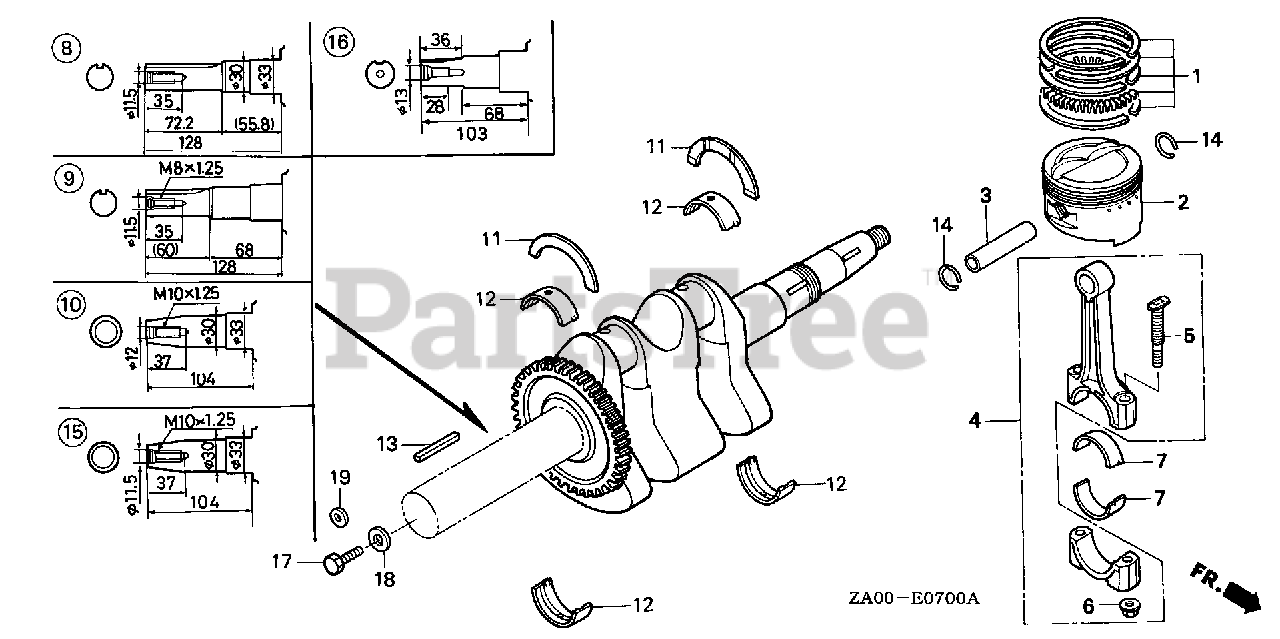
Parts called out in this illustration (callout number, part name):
1	RING SET, PISTON (STD) (RIKEN)
1	RING SET, PISTON (0.25) (RIKEN)
1	RING SET, PISTON (0.25) (TEIKOKU)
1	RING SET, PISTON (0.50) (TEIKOKU)
2	PISTON (STD)
2	PISTON (0.25)
2	PISTON (0.50)
3	PIN, PISTON
4	ROD ASSY., CONNECTING
5	BOLT, CONNECTING ROD
6	NUT, CONNECTING ROD
7	BEARING A, CONNECTING ROD (BLACK)
7	BEARING B, CONNECTING ROD (BROWN)
7	BEARING C, CONNECTING ROD (GREEN)
7	BEARING D, CONNECTING ROD (YELLOW)
7	BEARING E, CONNECTING ROD (RED)
11	BEARING, CRANKSHAFT THRUST
12	BEARING, CRANKSHAFT (BLACK)
12	BEARING, CRANKSHAFT (BROWN)
12	BEARING, CRANKSHAFT (GREEN)
12	BEARING, CRANKSHAFT (YELLOW)
12	BEARING, CRANKSHAFT (RED)
14	CLIP, PISTON PIN (14MM)
15	CRANKSHAFT
